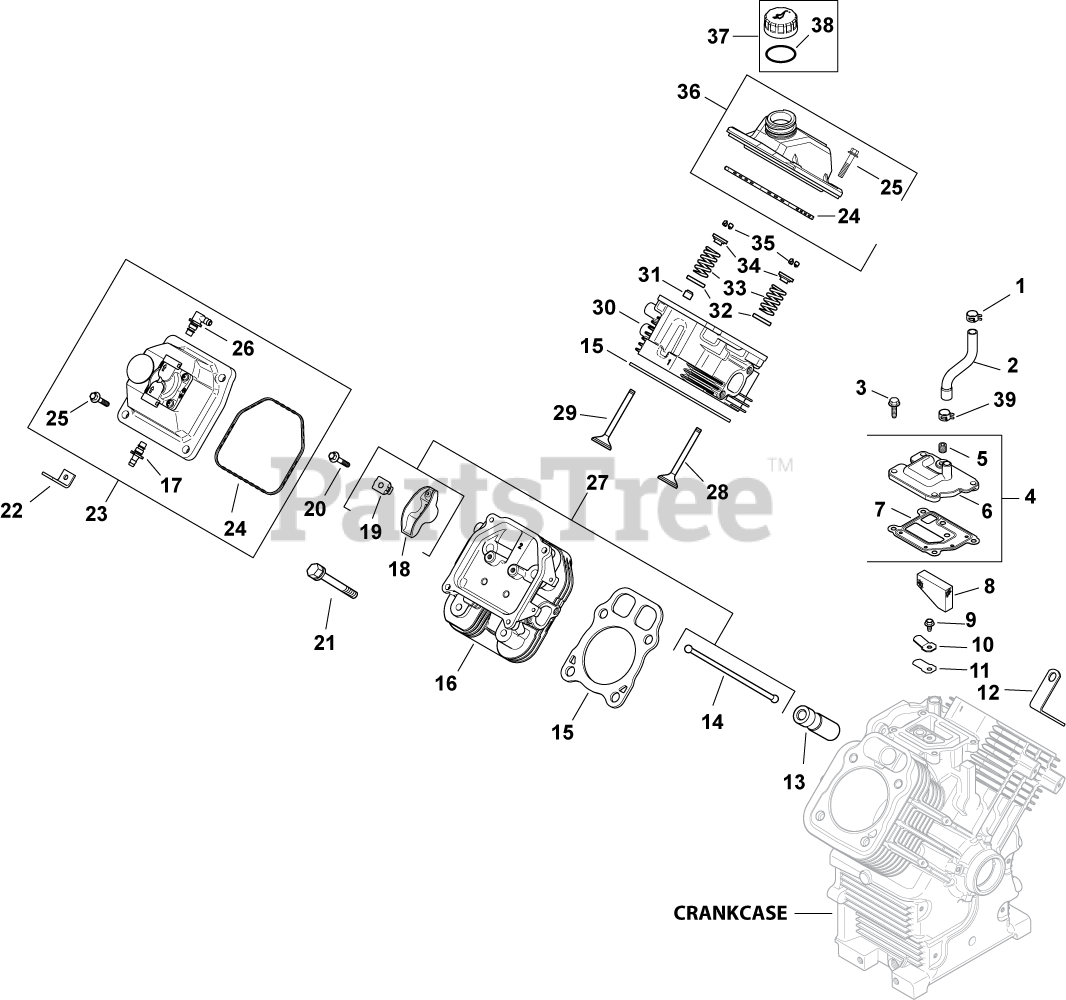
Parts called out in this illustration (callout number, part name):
1	CLAMP, BAND SPRING HOSE-(#2523737S)
2	HOSE, BREATHER
3	SCREW,FLG THD FRM M6X1.0X20-(#25086396S)
4	KIT, BREATHER ASSEMBLY
5	PLUG, CTSK PIPE 1/8"
6	COVER, BREATHER -USE 24 033 01-S
7	GASKET, BREATHER-USE 24 041 67-S
8	FILTER, BREATHER
9	SCREW, FLG THD FRM M5X.8X10
10	RETAINER, REED
11	REED, BREATHER
12	STRAP, LIFTING-USE 25 445 03-S
13	LIFTER, HYDRAULIC VALVE-USE 25 351 10-S
14	ROD, PUSH
15	KIT, GSKT CYL HD (C22-23 674CC)
16	KIT, CYLINDER HEAD #2 USE 24 318 149-S
17	KIT, STRAIGHT FITTING
18	ARM, ROCKER
19	PIVOT, ROCKER ARM
20	SCREW, FLG M6X1.0X34
21	SCREW, FLG M8X1.25X45
22	STRAP, LIFTING
23	KIT, VALVE COVER-FUEL PUMP
24	O-RING (YELLOW), VALVE COVER
25	SCREW, FLG M6X1.0X30
26	KIT, 90 DEG. FITTING
27	KIT, VALVE TRAIN
28	VALVE, INTAKE (STD)
29	VALVE, EXHAUST (STD) - USE 32 016 01-S
30	KIT, CYLINDER HEAD #1 - (#24318143S)
31	SEAL, VALVE STEM - (#2503214S)
32	RETAINER, SPRING
33	SPRING, VALVE
34	RETAINER, VALVE SPRING - USE 25 173 28-S
35	KIT, RETAINER
36	KIT, VALVE COVER-OIL FILL
37	KIT, OIL FILL CAP (YELLOW)
38	O-RING, DIPSTICK
39	CLAMP, HOSE (KM)-USE 25 237 31-S
2401602-S	VALVE, EXHAUST (.25)
2401702-S	VALVE, INTAKE (.25)
